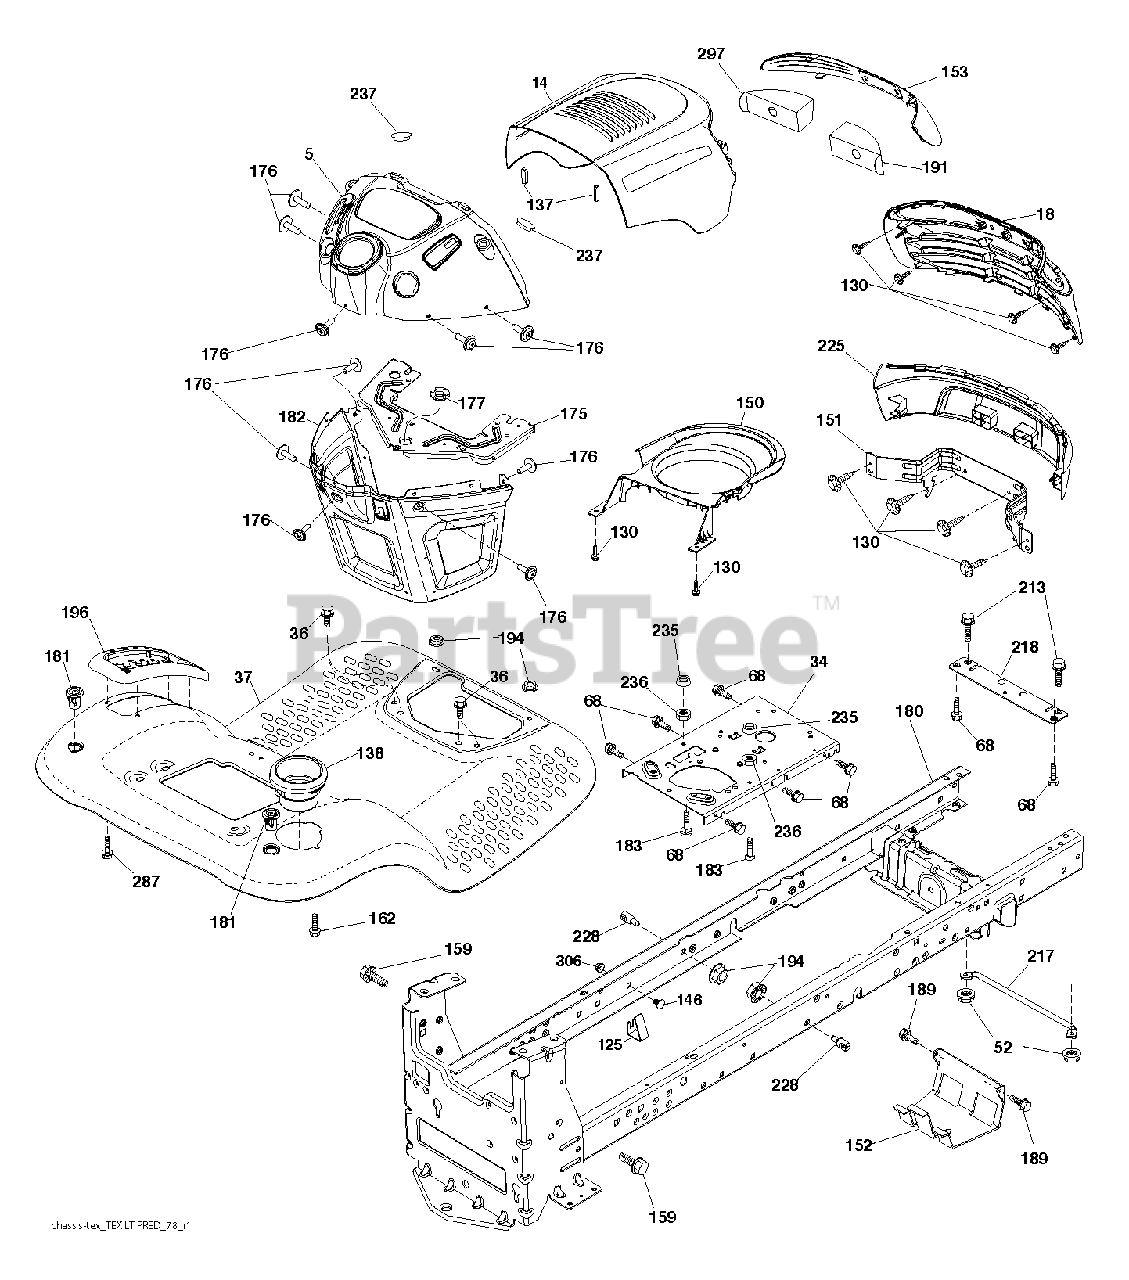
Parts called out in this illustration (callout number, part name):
5	DASH.PRED.LT.CC.ICY.N/SRV.BLK
14	HOOD.PREDATOR.LT.U-FORM.TOPVN
18	GRILLE.SVC.BASE.PREDATOR.LT428
34	PLATE.ENGINE.WELDED.CHASSIS
36	SCREW 5/16"
52	LOCKNUT
68	SCREW LT
125	CLIP.FUEL.LINE
130	SCREW.#10 X 0.750.BOS (2 2)
137	BUMPER.HOOD.TEX.HUSQVARNA
138	CUPHOLDER.TL.TEX.BLACK
146	BOLT.RDHD.SHT.SQNK.3/8-16X5/8
150	DUCT.AIR.TOP.VENT.PREDATOR.LT
151	BRACKET.PIVOT.ALPHA.LT
152	SHIELD.BROWNING.W/TEX
153	LENS.PREDATOR.LT.
159	SCREW, 3/8-16X3/4
162	SCREW.HI-LO.CONSOLE
175	CROSSMEMBER
176	SCREW.#10-24X5/8.RN.QU
177	BUSHING STEERING
180	CHASSIS
181	FEND/FTRST.PCH.CPH.NFW
182	DASH.LOWER.PREDATOR LT
183	BOLT.5/16-18X1-1/4 FULL THD
189	SCREW
191	INSERT.REFLECT.PREDATOR.LT.RH
194	NUT LOCK HEX FLANGE 5/16-18
213	BOLT
217	ROD.PIVOT.HOOD
218	X-PIECE.HOOD.STOP.NON/
228	STUD.FASTNER.W/ANTI-ROTATE
235	SPACER FENDER
236	NUT.CENTERLOCK.5/16-
237	PLUG.MOUNT.CARGO.BLK
287	SCREW 1/4X20
297	REFLECTOR.INSERT.PRED.LH.LT
306	NUT LOCK FLG 3/8-16 UNC
